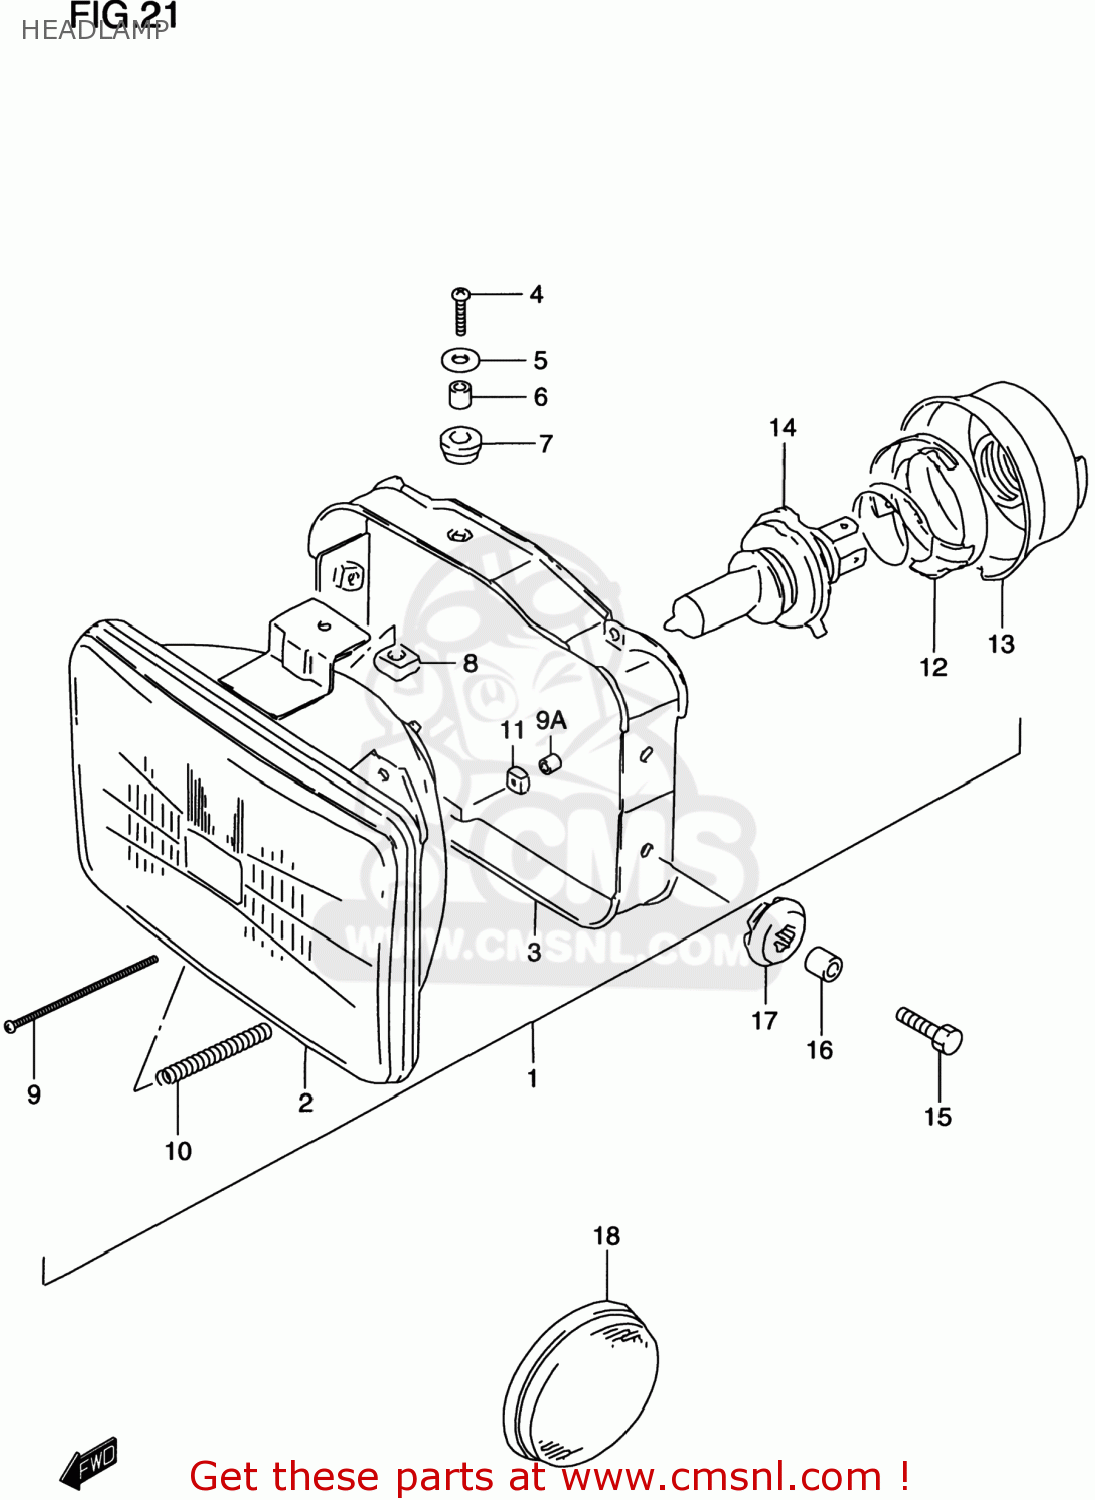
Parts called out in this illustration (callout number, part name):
1	HEADLAMP ASSEMBLY
2	LAMP UNIT
3	HOUSING
4	SCREW
5	WASHER(5.5X18X1)
6	SPACER
7	CUSHION
8	NUT
9	SCREW
9A	CAP,SCREW
10	SPRING
11	NUT,HEADLAMP ADJUST
12	HOLDER,BULB
13	COVER,SOCKET
14	BULB(12V60/55W,H4)
15	BOLT(6X20)
16	SPACER(6.5X9X9)
17	CUSHION
18	REFLECTOR,REFLEX FR
